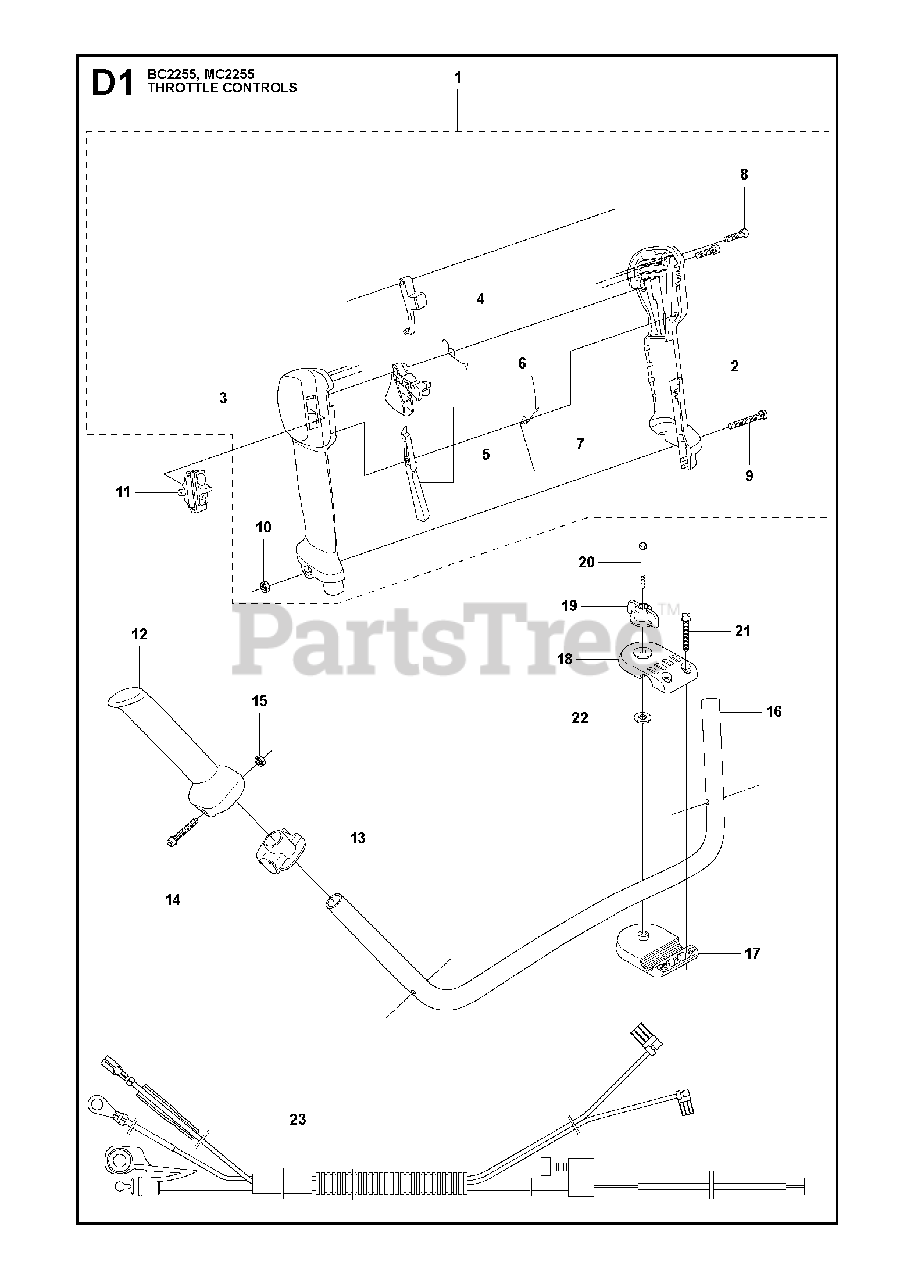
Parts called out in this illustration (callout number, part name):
1	THROTTLE HANDLE ASSY
2	HANDLE HALF RIGHT
4	SWITCH
5	THROTTLE CONTROL
6	SPRING
7	SPRING
8	SCREW
9	%SCREW
10	NUT
11	STOP BUTTON
15	NUT M6M M5
16	HANDLE
17	HANDLE BRACKET
18	HANDLE BRACKET
20	SCREW 6X70
23	WIRING
